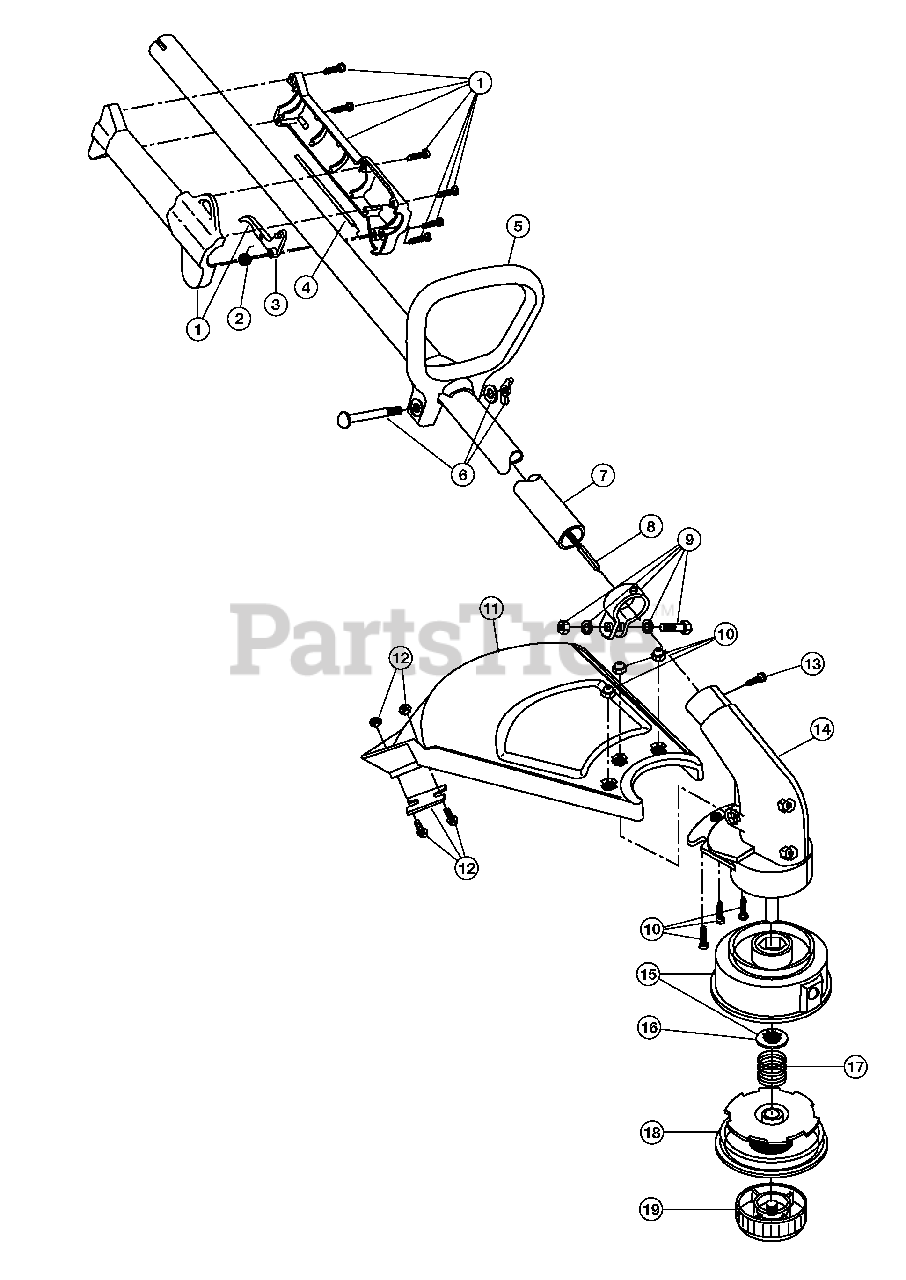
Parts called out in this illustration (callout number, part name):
1	Throttle Housing & Trigger Assembly
2	Throttle Trigger Spring
3	Throttle Trigger
4	Throttle Cable Housing Assembly
5	D-Handle
6	D-Handle Hardware Assembly
7	Drive Shaft Housing Assembly
8	Flexible Drive Shaft
9	Lower Clamp Assembly
10	Guard Mounting Screw Assembly
11	Guard and Blade Assembly
12	Blade Assembly
13	Anti-Rotation Screw
14	Gearbox Assembly
15	Outer Spool Assembly
16	Retainer
17	Spring
18	Inner Reel
19	Bump Head Knob Assembly
